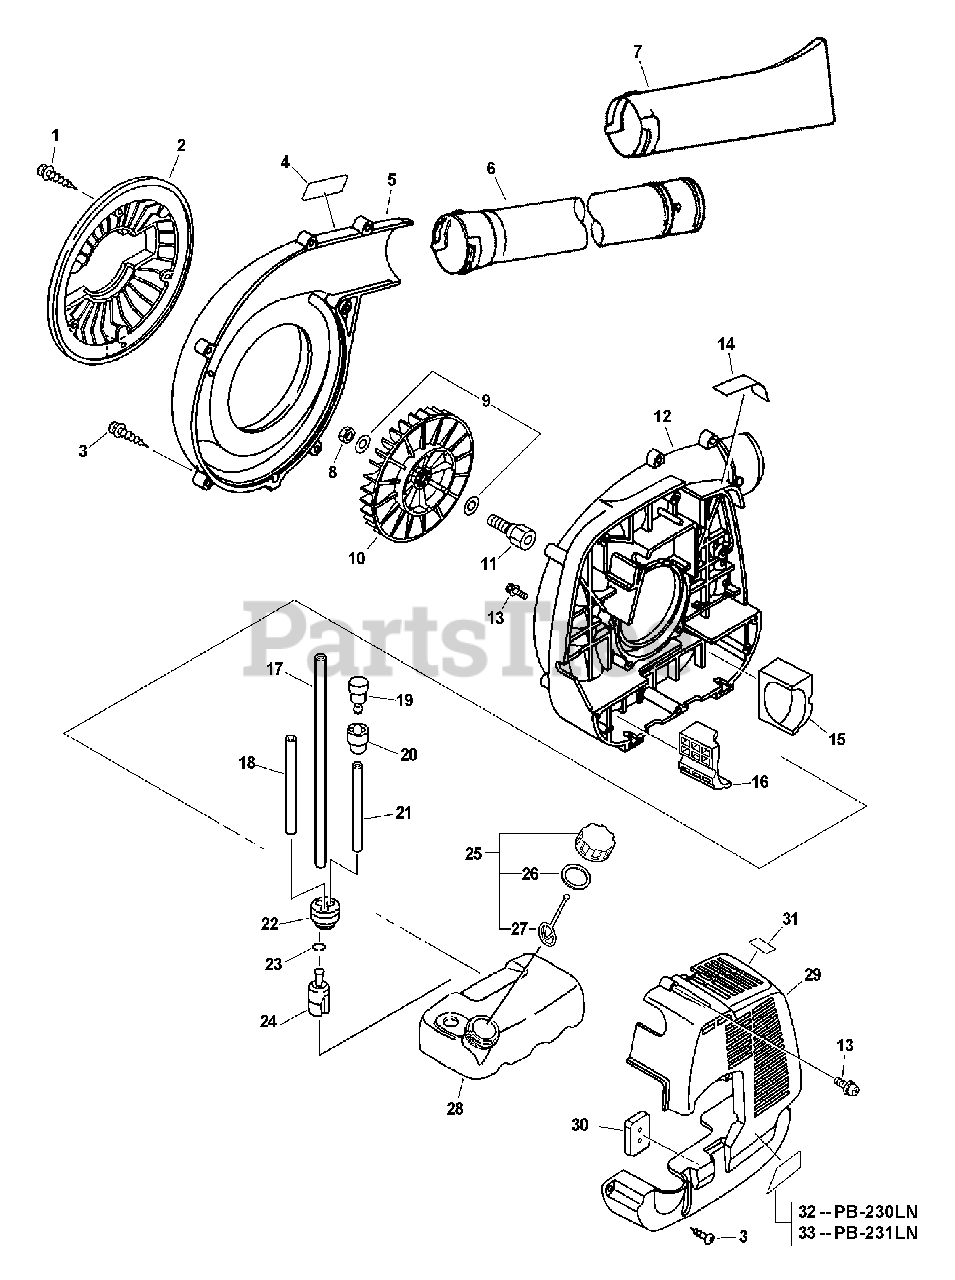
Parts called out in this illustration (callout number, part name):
1	SCREW 5×16
2	SHIELD, DEBRIS
3	SCREW, TAPPING 5×20
4	LABEL, NOISE
5	COVER, FAN - OUTER
6	TUBE, BLOWER - STRAIGHT
7	TUBE, BLOWER
11	HUB, FAN
12	COVER, FAN - INNER
13	BOLT 5×20
14	LABEL, CAUTION - ISO
15	CUSHION
16	CUSHION
17	PIPE, FUEL 3×6×200
18	PIPE, FUEL 3×6×100
19	VENT ASSY
20	HOLDER, VENT
21	PIPE, FUEL 3×6×100
22	GROMMET, FUEL
23	CLIP Ø6.5 MM
24	FILTER, FUEL
25	CAP ASSY, FUEL
26	GASKET, FUEL CAP
27	CONNECTOR, CAP L= 100 MM
28	TANK, FUEL
29	COVER, ENGINE
30	CUSHION
31	LABEL, CAUTION - HOT
32	LABEL, MODEL
33	LABEL, MODEL
